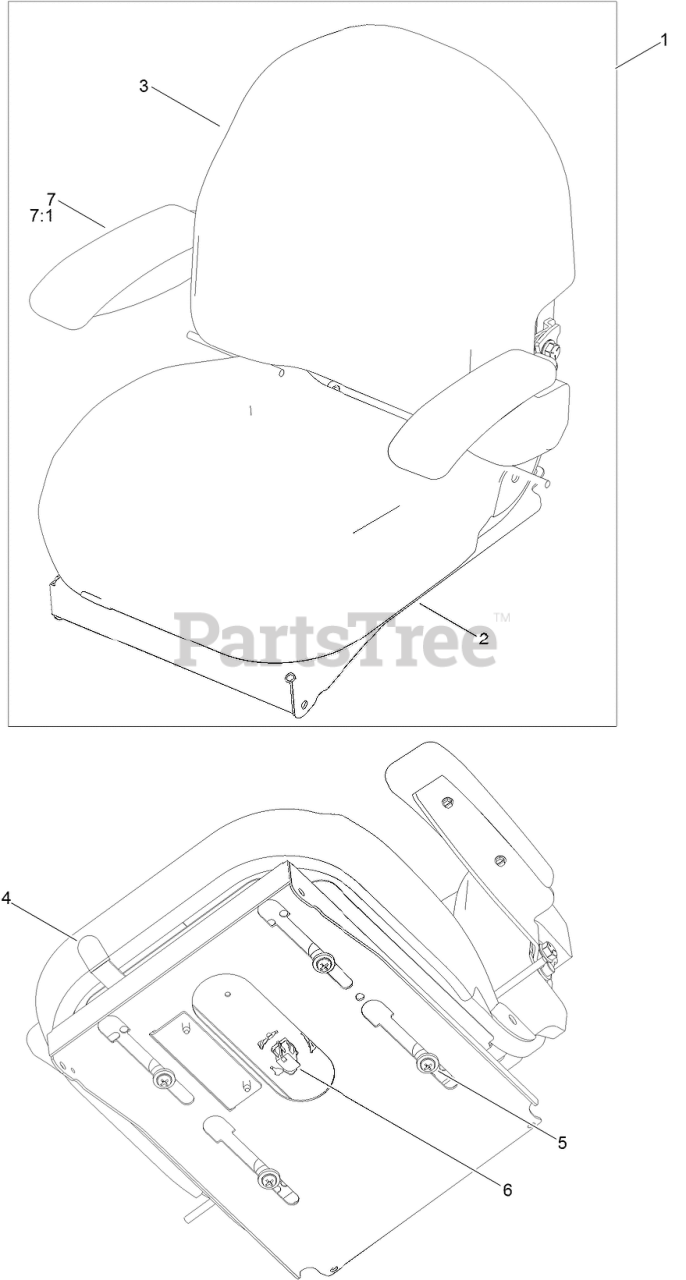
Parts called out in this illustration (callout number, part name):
1	Seat ASM
2	Cover-Base
3	Cover-Back
4	TRACK ASM
5	BUSHING ASM
6	SWITCH-BAIL
7	ARMREST KIT
7:1	CUSHION-REST, ARM
